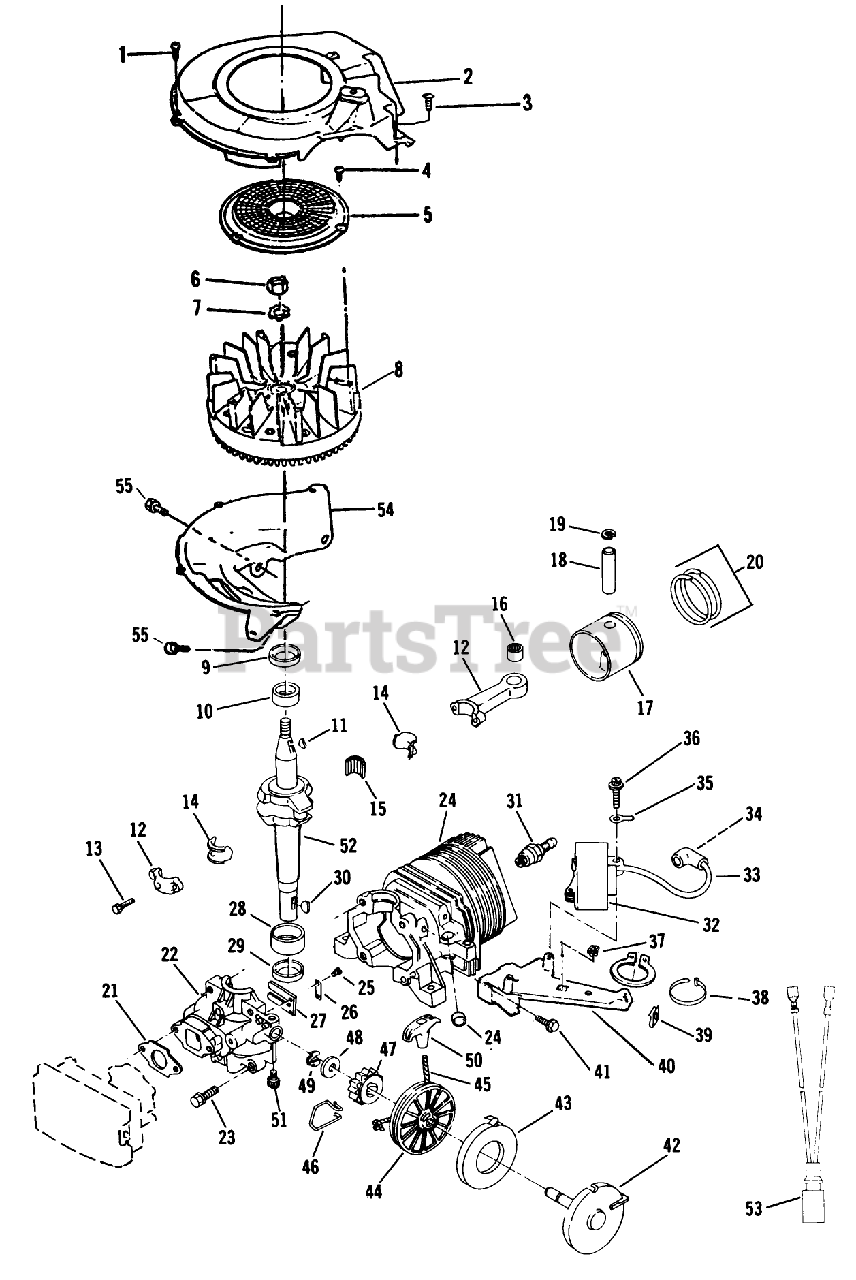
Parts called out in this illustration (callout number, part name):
1	SCREW S
3	SCREW F
4	SCREW F
6	NUT
10	BEARING V
11	KEY
13	Screw
14	LINER ASM
16	BEARING AY F
19	RING-RETAINING
21	GASKET CARB S
23	SCREW S
24	PLUG-CORE VF
26	PLATE-BACKUP, REED
28	BEARING V
29	SEAL-OIL
33	HT LEAD&COVER XEV
35	TERMINAL S
37	NUT-CLIP
39	NUT - SPEED S
44	PULLEY STARTER S
46	SPRING F
48	WASHER S
50	HANDLE STARTER S
53	WIRE HARNESS
54	SHROUD BASE S
55	SCREW-SEMS
